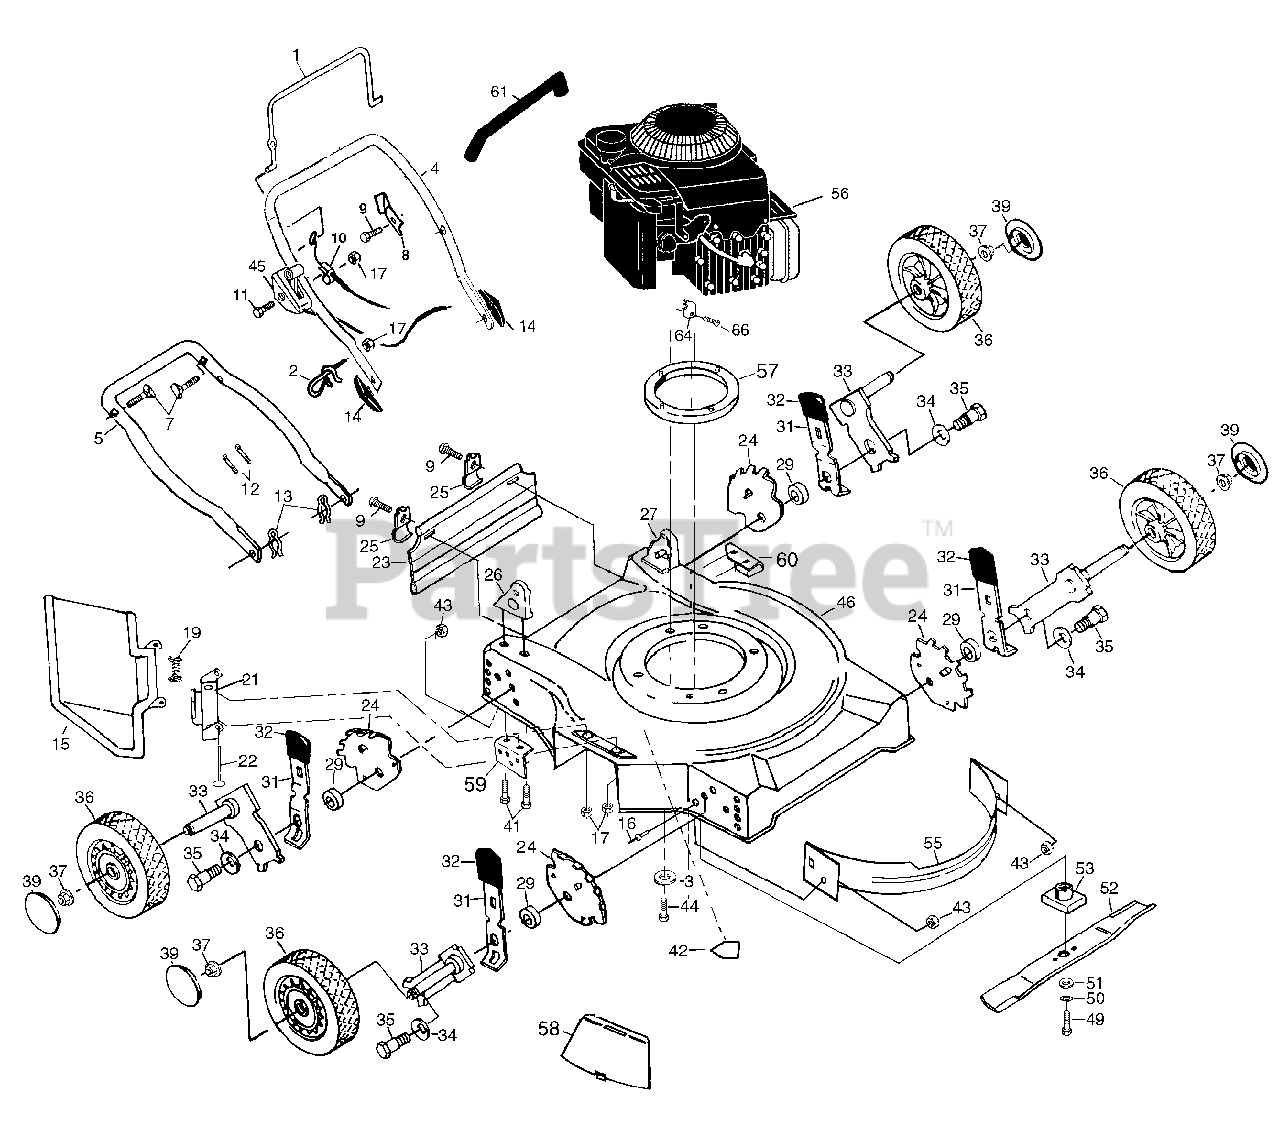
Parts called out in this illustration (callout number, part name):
1	Control Bar
2	Rope Guide
3	Engine Washer
4	Upper Handle
5	Lower Handle
7	Handle Bolt
8	Up-Stop Bracket
9	Hex Washer Head Screw #10-24 x 1/2
10	Engine Zone Control Cable
11	Screw Hex Hd 1/4 x 2- 1/8
12	Wire Tie
13	Hairpin Cotter
14	Handle Knob
15	Discharge Guard
17	Locknut 1/4-20
19	Torsion Spring
21	Bracket Assembly
23	Rear Deflector
24	Wheel Adjusting Bracket
25	Deflector Bracket
26	Handle Bracket Assembly (Right)
27	Handle Bracket Assembly (Left)
29	Spacer
31	Selector Spring
32	Selector Knob
33	Axle Arm Assembly
34	Belleville Washer
35	Shoulder Bolt
36	Wheel and Tire Assembly
37	Nut
41	Thread Cutting Screw 5/16-18 x 3/4
42	Danger Decal
43	Locknut 3/8-16
44	Hex Head Thread Rolling Screw 3/8-169 x 1-1/8
45	Throttle Control
46	Lawn Mower Housing
49	Hex Head Screw 3/8-24 x 1-3/8 (Grd.8)
50	Helical Lock Washer 3/8
51	Hardened Washer
53	Blade Adapter
55	Front Baffle
57	Spacer Ring
58	Mulcher Plate
59	Bracket Support (Right)
60	Bracket Support (Left)
61	Handle Grip
64	Cable Clamp
66	Screw #10 x 5/8
